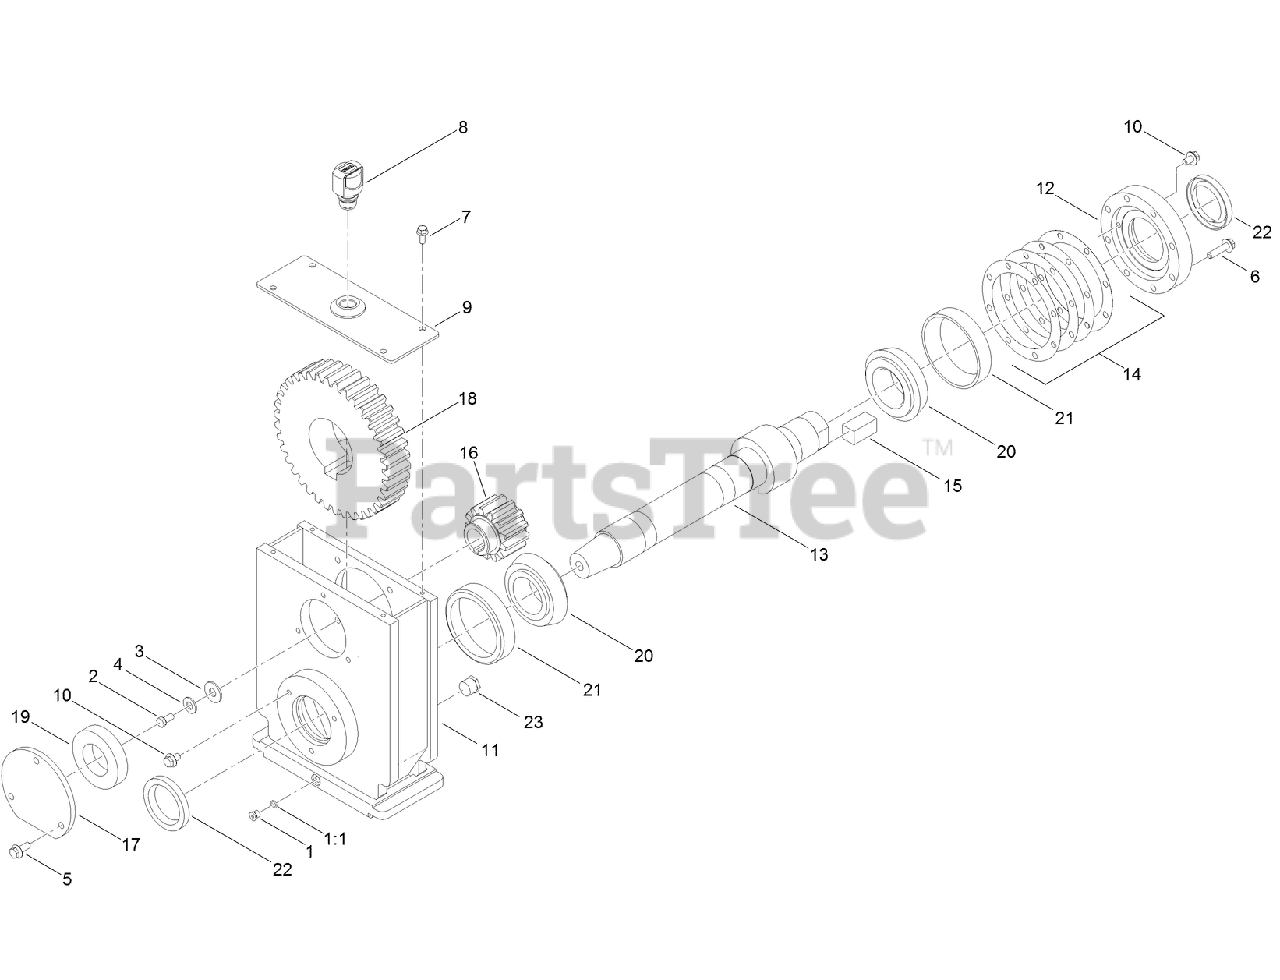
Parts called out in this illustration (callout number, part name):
1	PLUG ASM
1:1	O-RING
2	SCREW-HH
3	WASHER-FLAT
4	WASHER-FLAT
5	SCREW-HHF
6	SCREW-HHF
7	SCREW-HHF
8	BREATHER
9	ROTARY BOX COVER
10	SCREW-HHF
11	BOX-ROTARY
12	PLATE-BEARING CAP
13	SPINDLE-ROTARY
14	SHIM-ROTARY BEARING (.010 THICK)
15	KEY-ROTARY BOX
16	GEAR-PINION, ROTARY BOX (13T)
17	PLATE-RETAINING, ROTARY BOX
18	GEAR-RING, ROTARY BOX (38T)
19	BEARING-RADIAL BALL
20	CONE-BEARING
21	CUP-BEARING
22	SEAL-SHAFT
23	PLUG-SITE, GLASS
